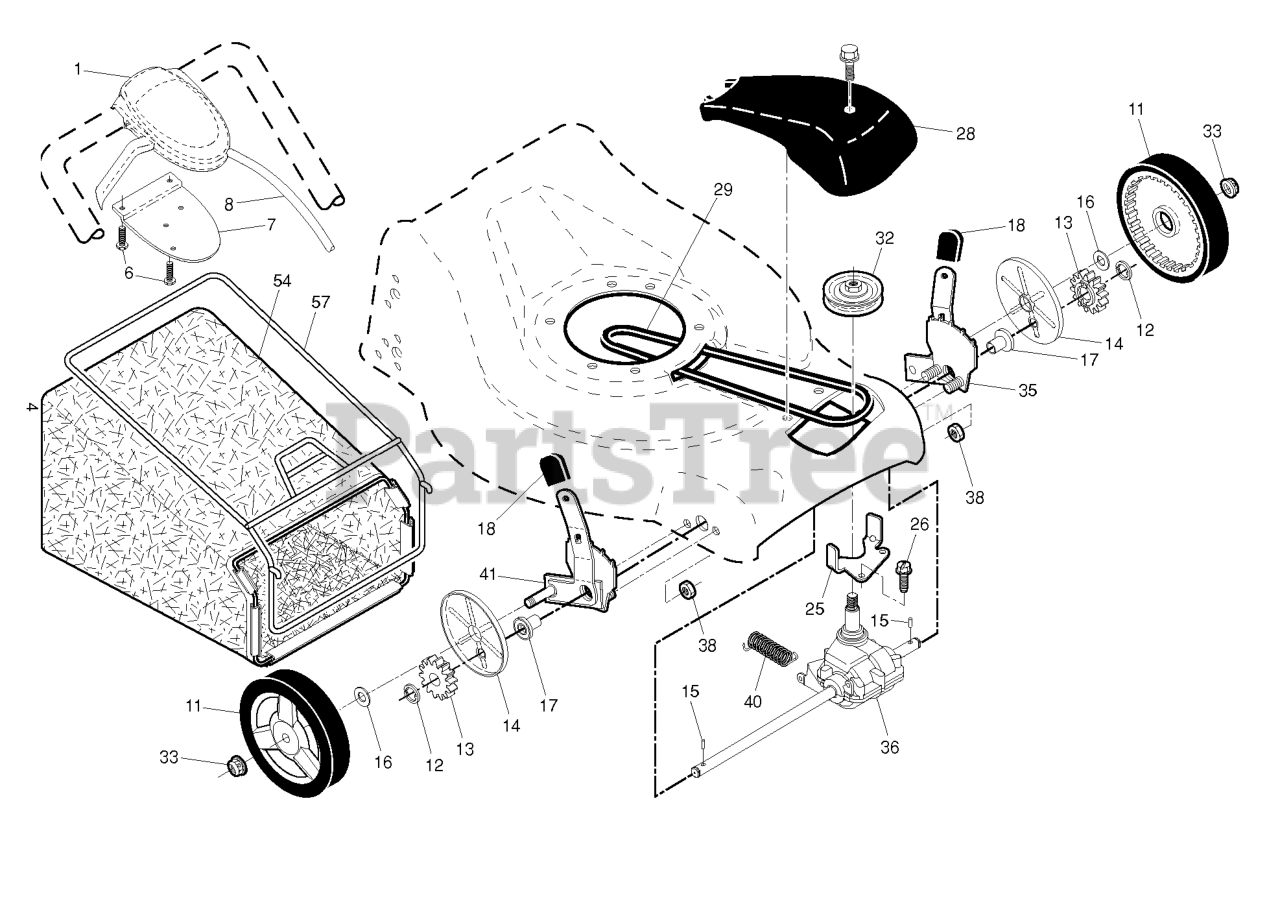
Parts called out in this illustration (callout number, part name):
1	CONTROL.DR.QW.21FGD.BS.GY/BLK
6	SCREW, PHILLIPS HEAD 10 X 5/8
7	BRACKET.DRIVE.CONTROL.MOUNT.BL
8	CABLE ASSEMBLY, DRIVE
11	WHEEL.8X1.75.H3SPK.RAD3.GY.BU3
12	E-RING 7/16 RE
13	PINION.14.TEETH.FGD
14	COVER.DUST.WHEEL
15	PAWL, DRIVE
16	WASHER FLUT
17	BEARING.ASM.
18	SELECTOR KNOB
25	BRACKET.BELT.GUIDE.22+FGD.BZP
28	COVER.DRIVE.ASM.185579.CE.WALK
29	RP PULLEY.DRIVE.EZ/VAR.SCREWON
32	RP PULLEY.DRIVE.EZ
33	NUT.HEX.FLANGE.3/8-16.LO(3 2)
35	KIT ADJUSTER ASM.438151.
36	TRANSMISSION.21.FGD.HT.VST
38	LOCKNUT.NYLOC.1/4-20
41	KIT ADJUSTER ASM.438148
54	Grassbag Assembly
57	FRAME.GBAG.21.FWGD
